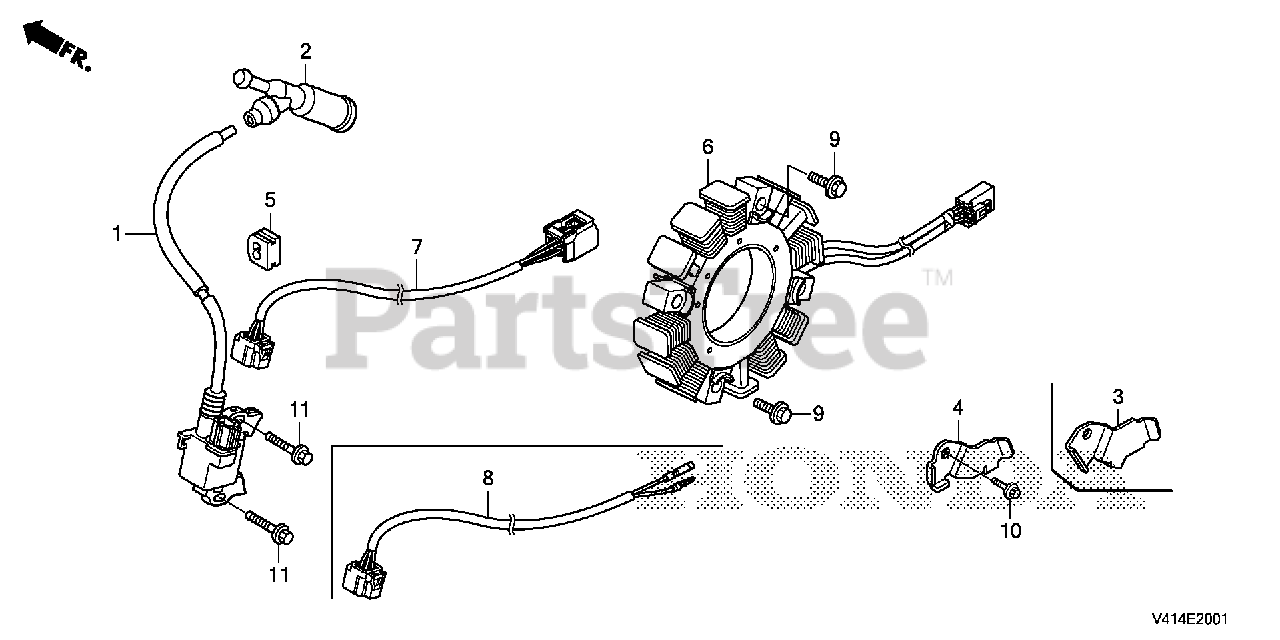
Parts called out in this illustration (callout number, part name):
1	COIL ASSY., IGNITION
2	CAP ASSY., NOISE SUPPRESSOR (NGK Y-EZD)
3	CLAMP, WIRE
5	GROMMET, WIRE
6	COIL ASSY., LAMP
8	WIRE HARNESS ASSY., ENGINE
9	BOLT, FLANGE (6X40)
10	BOLT, FLANGE (6X12) (CT200)
11	BOLT, FLANGE (6X28) (CT200) Use up to Engine SN 1530314.
